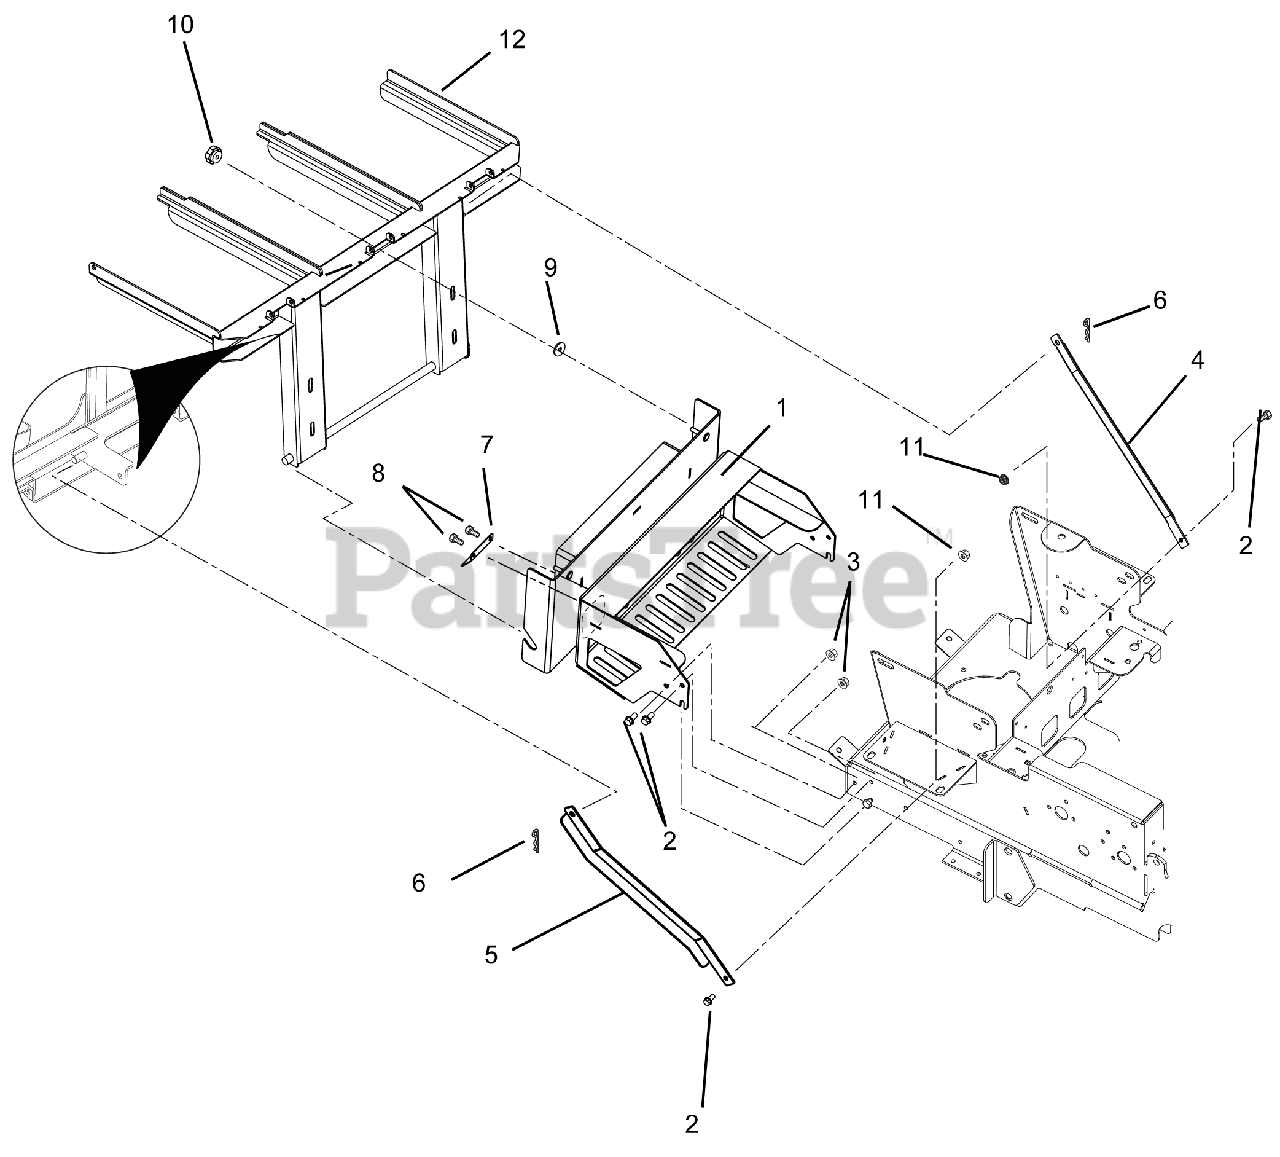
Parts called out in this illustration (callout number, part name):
1	WMT, HD BAGGER MOUNT
2	@BLT-HEX .38-16X1.00 GR5 YWZC
3	@NUT-LK-NYL-FLG .38-16 YWZC
4	WMT, LEFT BAGGER SUPPORT
5	WMT, RIGHT BAGGER SUPPORT
6	PIN-HAIR, ENDRIES #25 YWZC
7	SHIELD, HEAT DEFLECTION
8	@SCR-TAP .38-16X.50 HWH TR YWZ
9	@WSHR-FL-STL.563X1.38X.109YWZC
10	KNOB-CLAMPING, .312-18 NYLOC
11	@NUT-LK-CTR .38-16 YWZC
12	WMT, XL BAGGER FRAME
